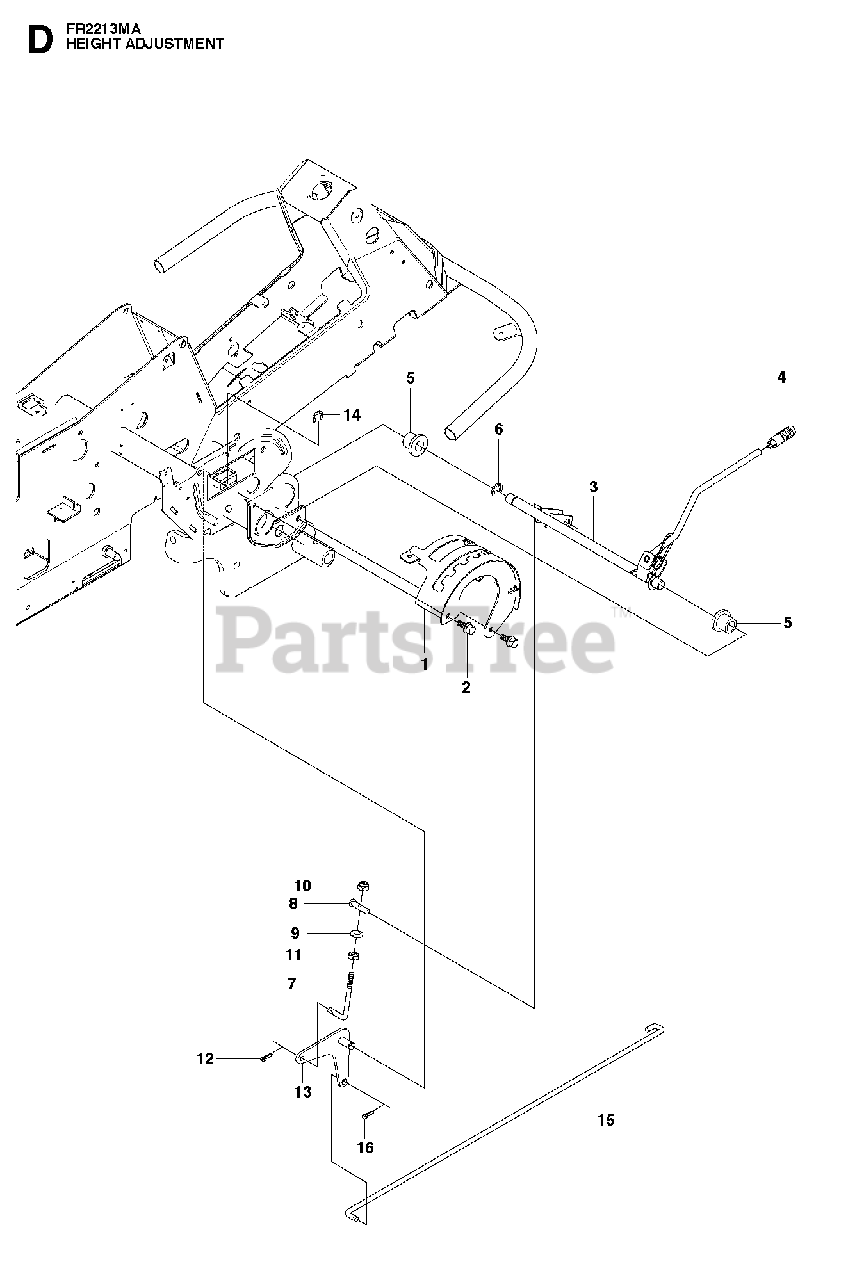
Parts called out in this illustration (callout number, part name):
4	GEAR STICK KNOB
5	BUSHING
9	WASHER
10	LOCKNUT M8
11	NUT
12	SPLIT PIN
14	RETAINING RING
16	SPLIT PIN
